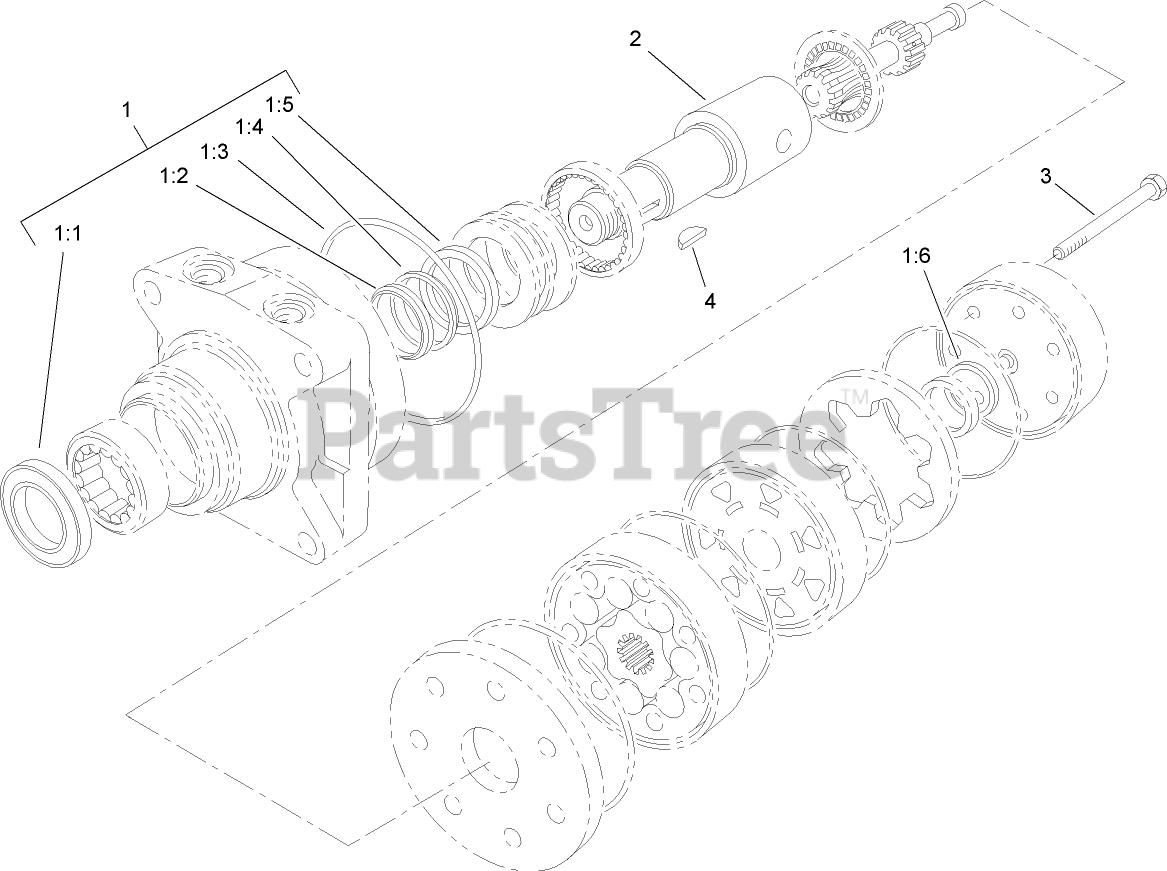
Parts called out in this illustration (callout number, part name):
1	SEAL KIT
1:1	Seal-Dirt and Water
1:2	BACKUP-RING
1:3	SEAL-SHAFT
1:4	Washer-Backup
1:5	SEAL-SQUARE, RING (INNER)
1:6	Seal-Commutator
2	SHAFT-COUPLING
3	SCREW-CAP, HH
4	KEY-WOODRUFF
